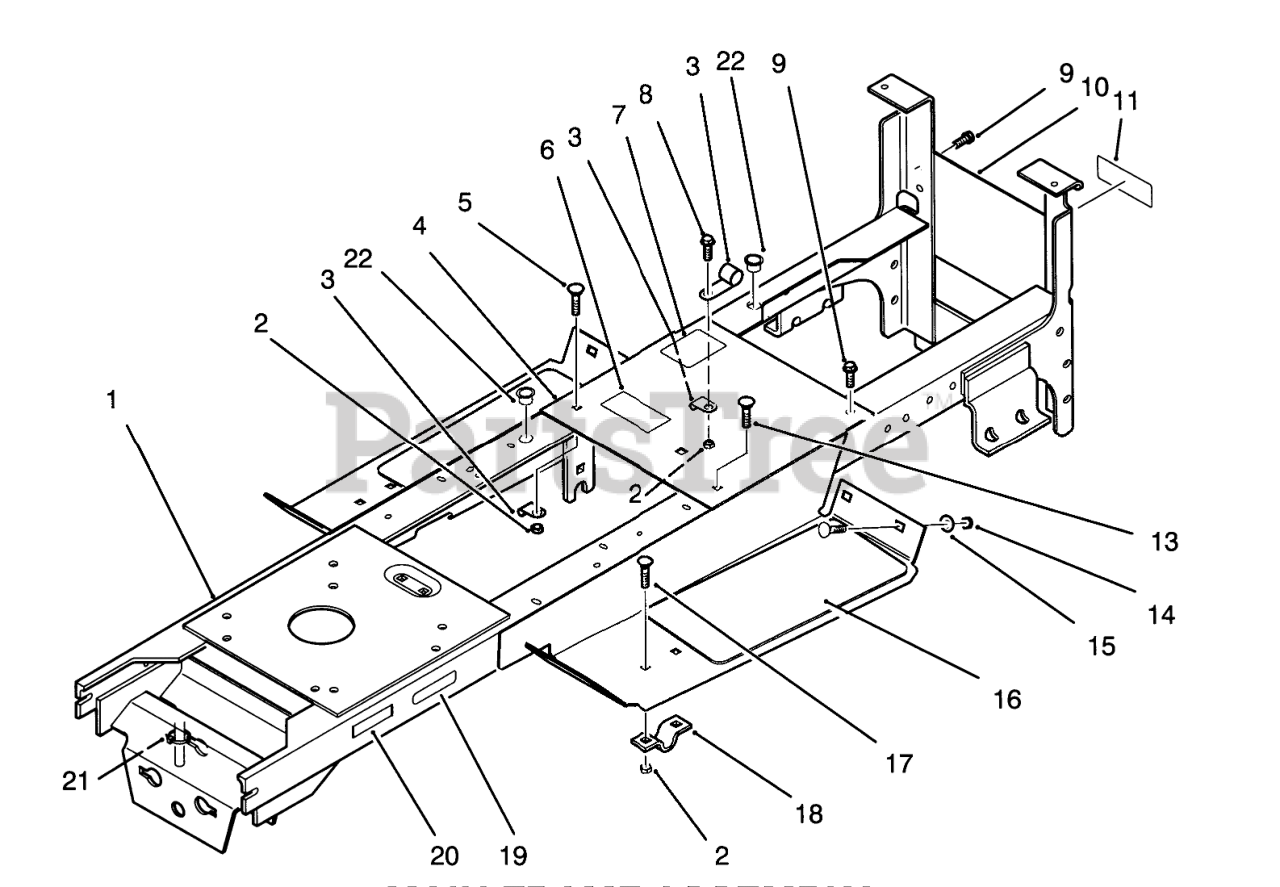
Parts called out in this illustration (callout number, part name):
1	Frame (Incl. Ref. #11)
2	NUT-LOCK, NI
3	THROTTLE CONTROL CLP
4	Panel (Incl. Ref. #6)
5	Bolt-Carriage
6	DECAL-DANGER
7	DECAL-PARKING BRAKE
8	Bolt
9	Screw
10	PANEL-REAR R
11	DECAL - DANGER
13	SCREW-CARR
14	NUT-HEX
15	WASHER - FLAT YZ
16	PAD FOOTREST
17	NUT-HEX, JAM
18	CLAMP
19	DECAL-INSTALL BELT
20	Decal-Attac-O-Matic
21	PLASTIC TIE
22	BUSHING
